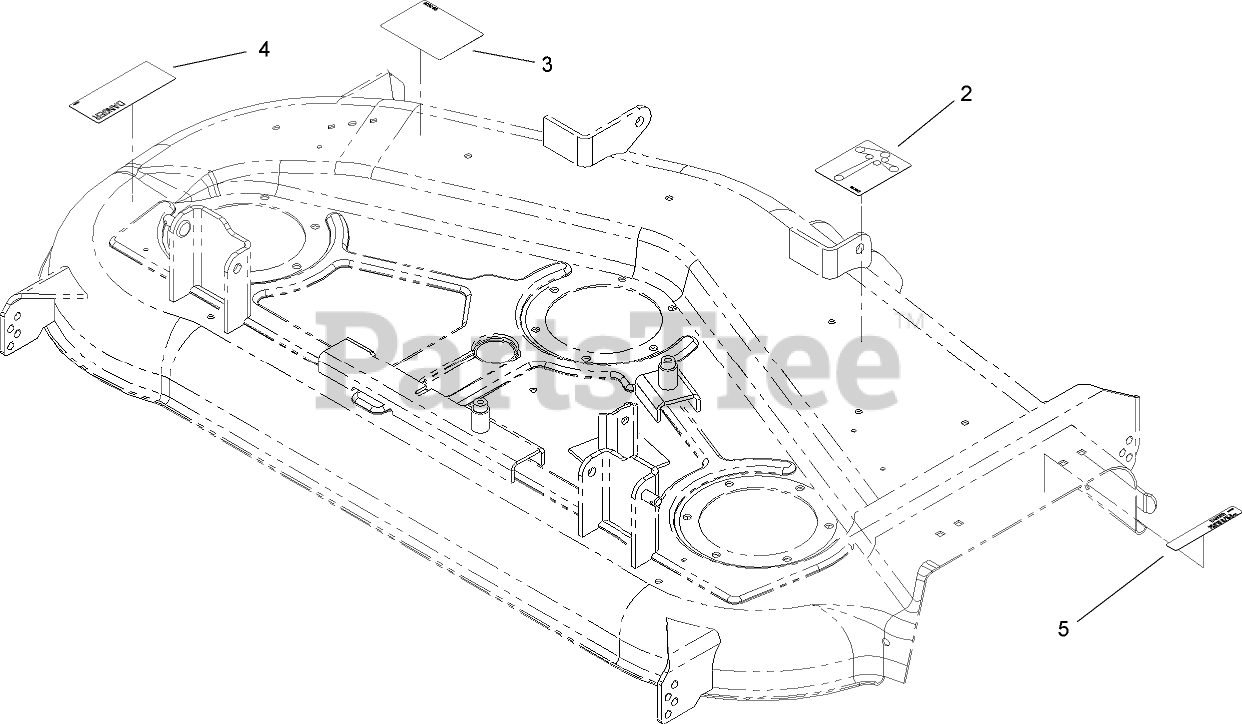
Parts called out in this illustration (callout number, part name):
2	DECAL-ROUTING, BELT
3	DECAL-ANTI SCALP
4	DECAL-DANGER
5	DECAL-DANGER
